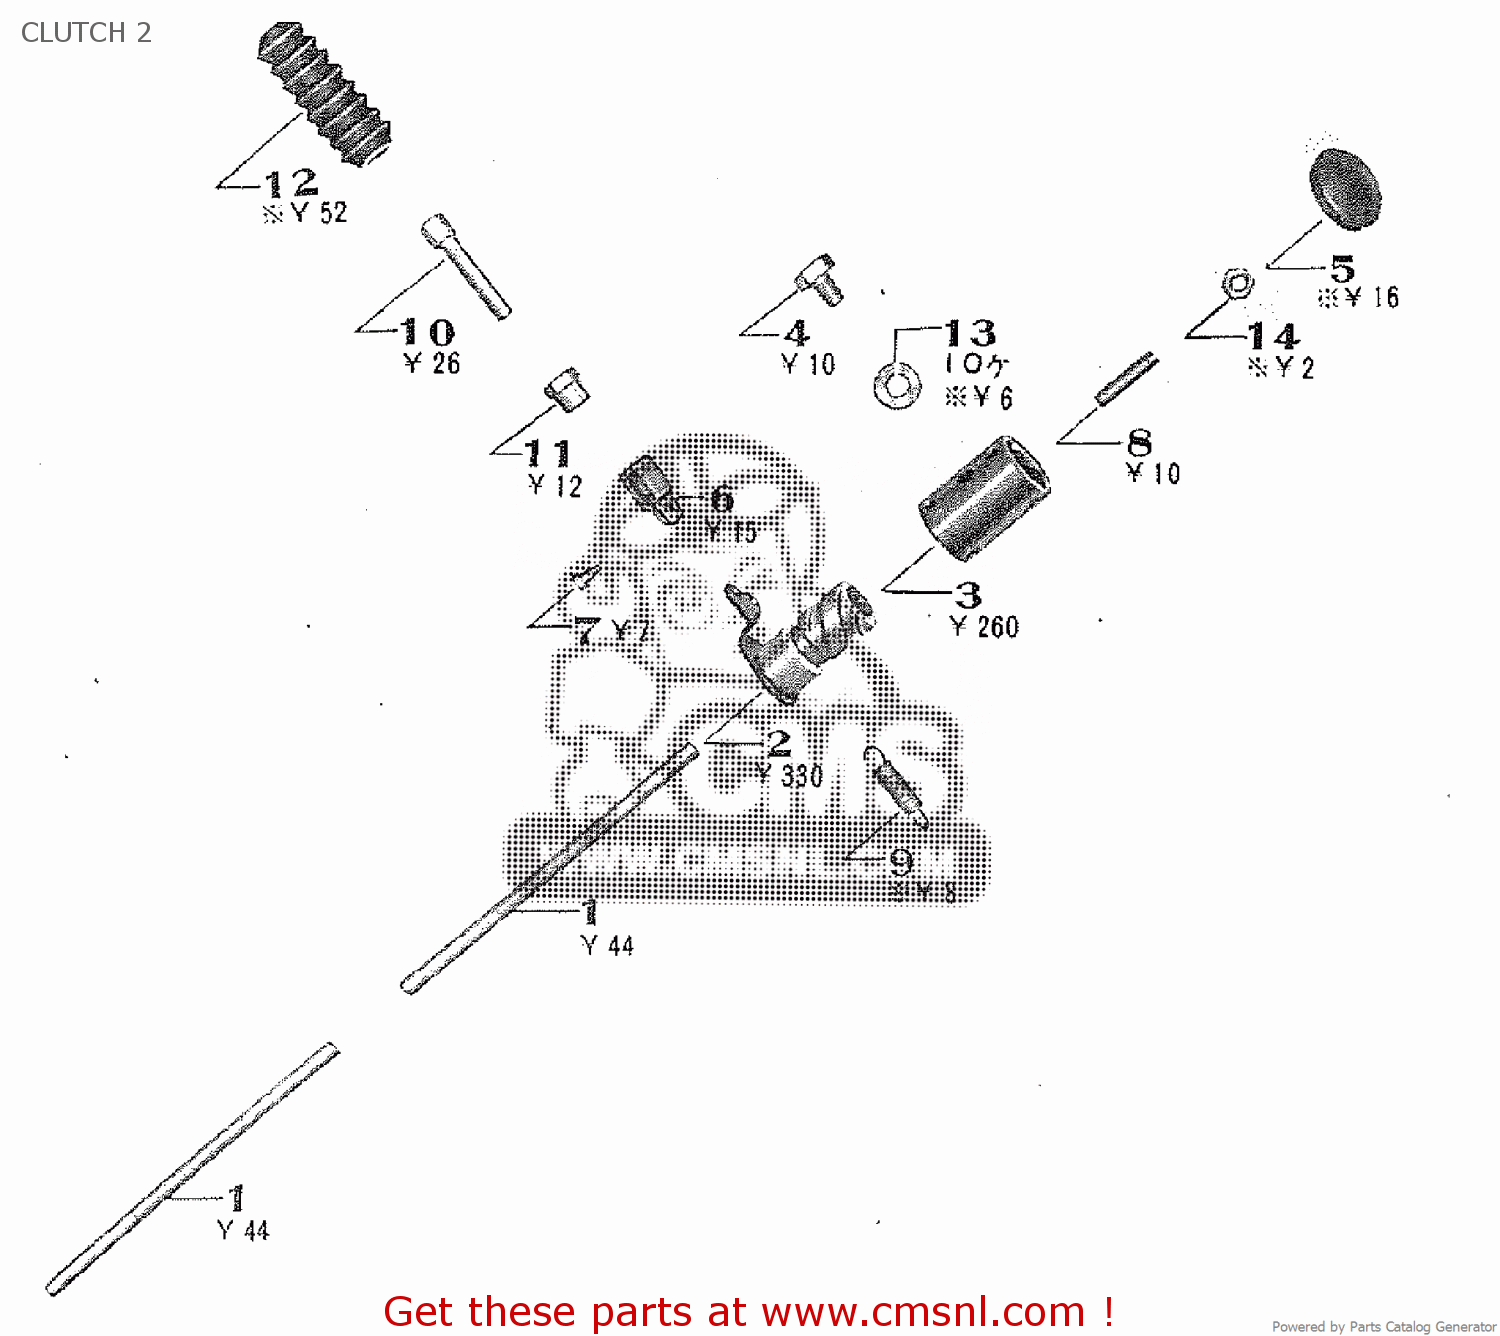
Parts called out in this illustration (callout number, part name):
1	CLUTCH PUSH ROD
2	RELEASE SCREW COMP.
3	RELEASE SCREW GUIDE
4	RELEASE SCREW GUIDE SET BOLT
5	RELEASE ADJUSTER CAP
6	RELEASE SCREW ARM HOOK
7	RELEASE SCREW ARM HOOK REVET
8	RELEASE SCREW ADJUSTER SCREW
9	RELEASE SCREW ARM RETURN SPRING
10	CLUTCH WIRE ADJUSTER
11	CLUTCH WIRE ADJUSTER NUT
12	CLUTCH WIRE BOOT
13	8MM SPRING WASHER
14	6MM HEXAGON NUT
